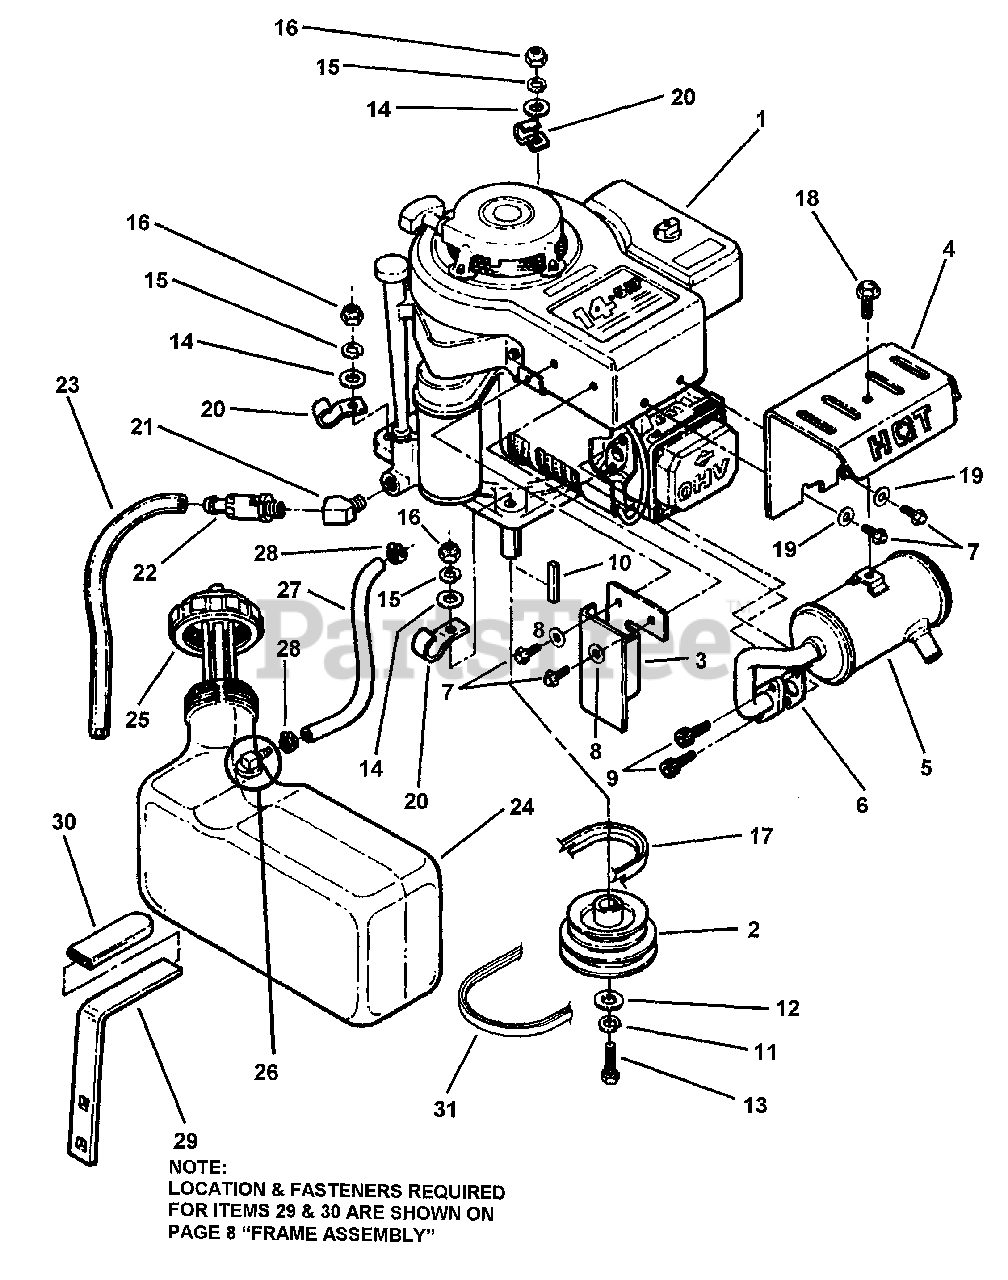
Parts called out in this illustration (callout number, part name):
1	* ENGINE, Briggs 14.5 HP (B&S 287707-1257-E1)
2	PULLEY, Engine, 38 Deck
3	SHIELD, Muffler
4	HEAT SHIELD, 14.5 HP Briggs Engine
5	MUFFLER, 14.5 HP
6	GASKET, Muffler
7	SCREW, 1/4-20 x 3/4" Hex Head Flange, Grade 5
8	WASHER, 1/4" I.D. x 5/8" O.D. x 1/16" Thick Flat
9	SCREW, 5/16-18 x 3/4" Socket Head Cap, Grade 8
10	KEY, 1/4" Square x 2"
11	WASHER, 7/16" Split Lock
12	WASHER, 7/16" I.D. x 1-3/8" O.D. x 1/4" Thick Flat
13	SCREW, 7/16-20 x 1-1/2" Hex Head Cap, Grade 5
14	WASHER, .344 I.D. x 1 1/16 O.D. x 1/16" Thick Flat
15	WASHER, 5/16 Split Lock
16	NUT, 5/16-24 Hex, Grade 5
17	BELT, Engine to Hydro (HA Section 28.814" EL)
18	BOLT, 5/16-18 x 1/2" Hex Flange Lock
19	WASHER, 1/4" I.D. x 1" O.D. x 1/8" Thick, Flat
20	WIRE CLIP, 7/16"
21	FITTING, 45 Degree, 3/8 Male-3/8 Female Oil Drain
22	ASSEMBLY, Oil Valve (Drain)
23	TUBING, 1/2 x 5/8 x 6" Clear (Drain)
24	ASSEMBLY, Fuel Tank
25	ASSEMBLY, Fuel Cap & Fuel Gage
26	ASSEMBLY, Fuel Pickup
27	HOSE, Fuel 1/4" I.D. x 13-1/2" long
28	CLAMP, Hose
29	BRACKET, Fuel Tank
30	COVER, Vinyl
31	BELT, Engine to Deck (HA section 60.32" EL)
